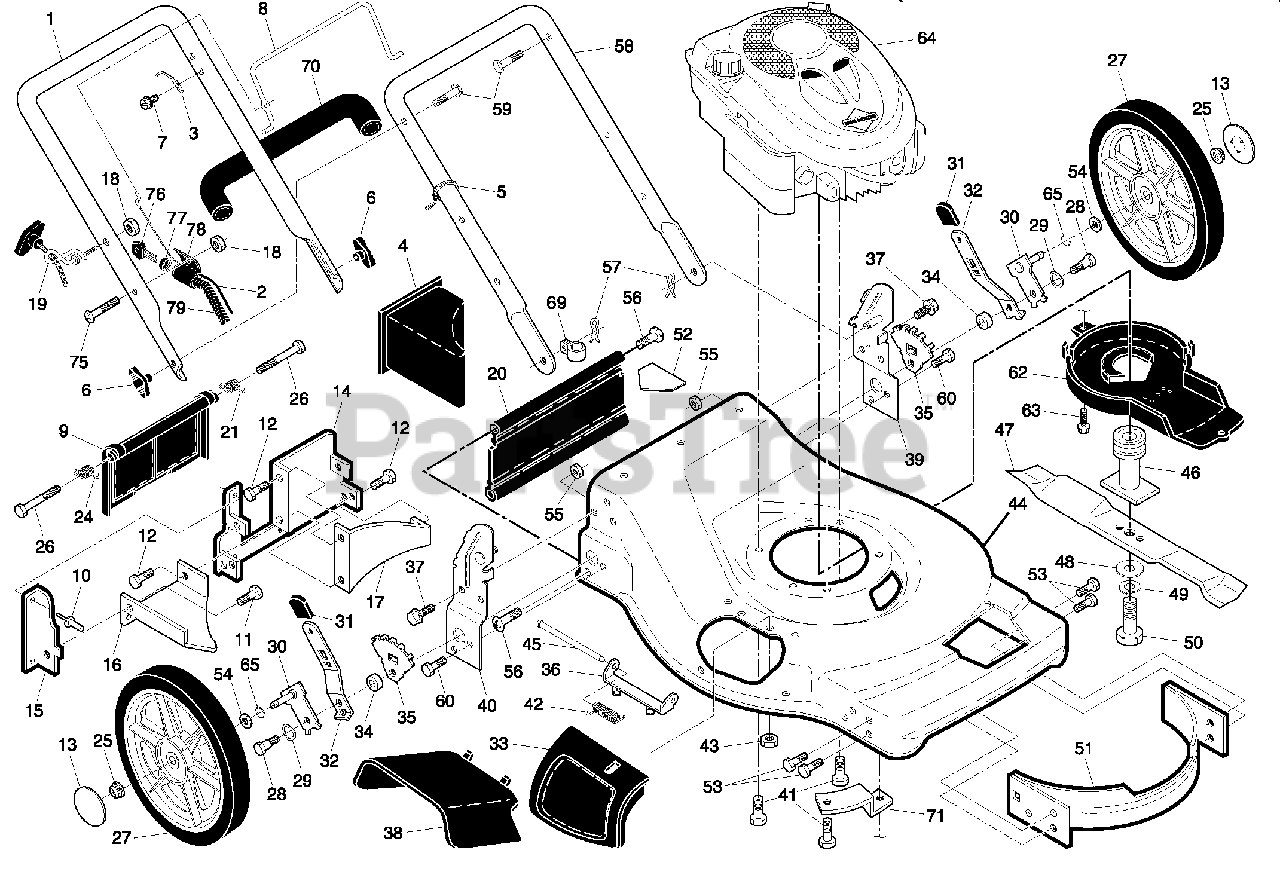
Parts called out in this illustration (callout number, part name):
1	Upper Handle Assembly
2	Cable, Operator Presence
3	Bracket, Upstop
4	Mulcher Plug
5	Wire Tie
6	Handle Knob
7	Screw
8	Control Bar
9	Rear Door Assembly
10	Pop Rivet
11	Screw, Self-Tapping #10-24 x 5/8
12	Screw, Hex Hex Head, Sems 1/4-20 x 1/2
13	Hubcap
14	Back Plate
15	Side Baffle
16	Discharge Baffle
17	Rear Baffle
18	Keps Locknut 1/4-20
19	Rope Guide
20	Rear Skirt
21	Spring, Rear Door, LH
24	Spring, Rear Door, RH
25	Nut, Hex, Flanged
26	Bolt, Rear Door
27	Wheel & Tire Assembly, Rear
28	Bolt, Shoulder 3/8-16 x 1
29	Washer, Curved, Cylindrical
30	Axle Arm Assembly
31	Selector Knob
32	Selector Spring
33	Mulcher Door
34	Spacer
35	Wheel Adjusting Bracket
36	Hinge Bracket Assembly
37	Screw, Sems, Thread Cutting 5/16-18 x 3/4
38	Discharge Deflector
39	Handle Bracket Assembly, LH
40	Handle Bracket Assembly, RH
41	Screw, Hex Head, Threaded, Rolled 3/8-16 x 1-1/8
42	Spring, Torsion
43	Nut, Hex, Nylock
44	Kit, Mower Housing
45	Rod, Hinge
46	Blade Adapter / Pulley
47	Blade, 22"
48	Washer, Hardened
49	Washer, Helical
50	Screw, Machine, Hex Head 3/8-24 x 1-3/8 Grade 8
51	Kit, Front Baffle
52	Danger Decal
53	Screw, Serrated, TT 1/4-20
54	Washer, Flat
55	Nut, Hex 3/8-16
56	Hinge Screw 1/4-20 x 1-1/4
57	Hairpin Cotter
58	Lower Handle
59	Handle Bolt
60	Bolt, Hex Head 3/8-16 x 3/4
62	Debris Shield
63	Screw, Debris Shield
65	O-Ring
69	Clip, Cable
70	Grip, Foam
71	Mounting Bracket, Debris Shield
75	Screw
76	Key
77	Nut, Cap
78	Key Start Switch
79	Wiring Harness
79	Operator's Manual, English
79	Operator's Manual, French
79	Repair Parts Manual
